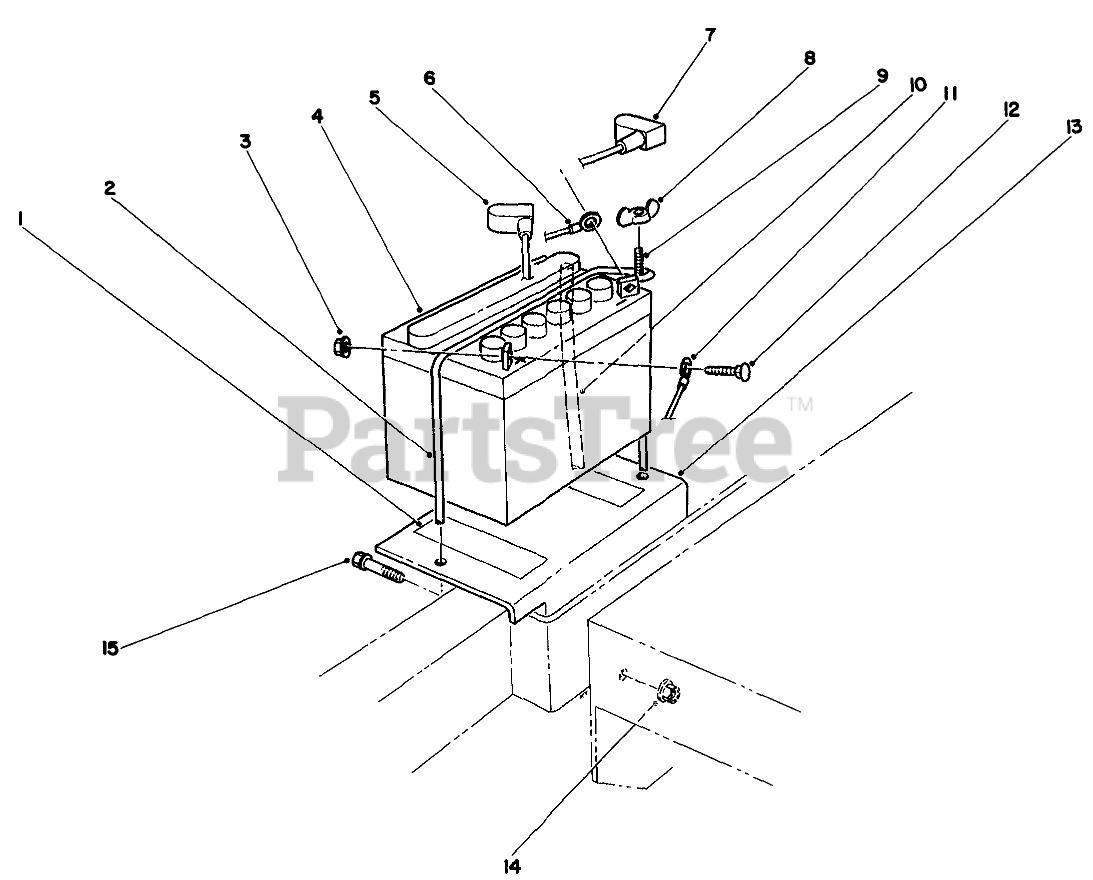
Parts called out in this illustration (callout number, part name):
1	PAD-TANK, FUEL
2	BATTERY CLAMP
3	NUT-KEPS
4	Battery
5	TERMINAL BOOT
6	WIRE ASM
7	BOOT-TERMINAL, RED
8	WING NUT
9	ROD-SUPPORT, BATTERY
10	TUBE-VENT
11	WIRE ASM
12	BOLT-CARR
13	BATTERY BRACKET B
14	NUT-HF
15	SCREW-HHF
